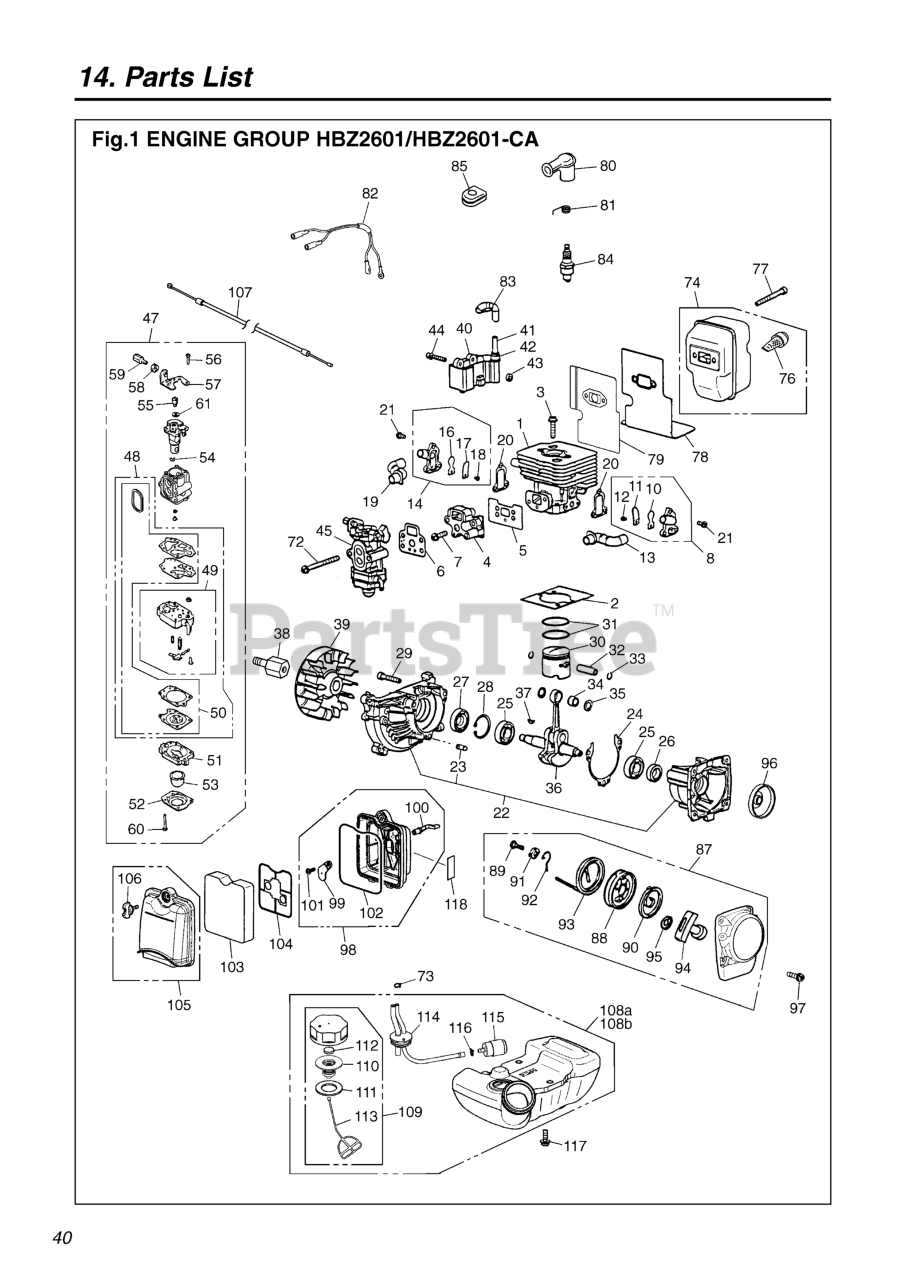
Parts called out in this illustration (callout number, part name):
1	CYLINDER
2	GASKET
3	BOLT
4	INSULATOR
5	GASKET INSULATOR
6	GASKET, CARBURETOR
7	BOLT (RPLS 2850-14220)
8	REEDVALVE (S) ASSY
10	REEDVALVE
11	STOPPER
12	SCREW, M3 x 8
13	PIPE, AIR S
14	REED VALVE ASSY-F
16	REEDVALVE
17	STOPPER
18	SCREW, M3 x 8
19	PIPE, AIR F
20	GASKET, VALVE
21	BOLT
22	CRANKCASE-C
23	PIN
24	GASKET
25	BEARING
26	SEAL
27	SEAL, OIL (RPLS 1140-21220)
28	RING, SNAP, M28 x 1.2
29	BOLT
30	PISTON
31	RING, PISTON
32	PIN
33	RING, SNAP (RPLS 1101-41320)
34	BEARING
35	WASHER
36	CRANKSHAFT COMP
37	KEY
38	EXTENSION
39	ROTOR
40	COIL-A
41	CORD (BLACK)
42	CAP
43	SPACER (RPLS -71260)
44	BOLT TORX
47	CARBURETOR ASSY
48	REBUILD KIT
49	BODY, PUMP
50	KIT, GASKET (REPLACES-06020)
51	BODY, PURGE
52	COVER, PUMP
53	PUMP, PRIMING
54	RING
55	SWIVEL
56	SCREW
58	NUT, CABLE ADJUSTER
59	SCREW, CABLE ADJUSTER
60	SCREW
61	WASHER
72	BOLT
73	CLIP
74	MUFFLER ASSY
76	ARRESTER
77	BOLT,TORX, M5X70
78	GASKET, MUFF
79	PLATE, MUFF
81	SPRING
83	TUBE
85	GROMMET
87	RECOIL ASSEMBLY
88	REEL
89	SCREW
90	SPRING, SPIRAL
91	COLLAR
92	ARM
93	ROPE (REPLACES 4500-75160)
94	KNOB (RPLS -75420)
95	PLATE, STOPPER
96	PULLEY
97	BOLT
98	BODY A
99	PLATE, CHOKE
100	LEVER
101	SCREW
103	ELEMENT
104	SCREEN (REPLACES -83K1)
105	COVER A (RPLS. T1513-82200)
106	KNOB
107	CABLE COMP (RPLS, -83100)
109	CAP ASSY (RPLS -85201)
110	HOLDER (REPLACES -85230)
111	PACKING
112	FILTER
113	STOPPER
114	PIPE COMPLETE
115	FILTER ASSY
116	CLIP (REPLACES 2841-31280)
117	BOLT
118	LABEL
